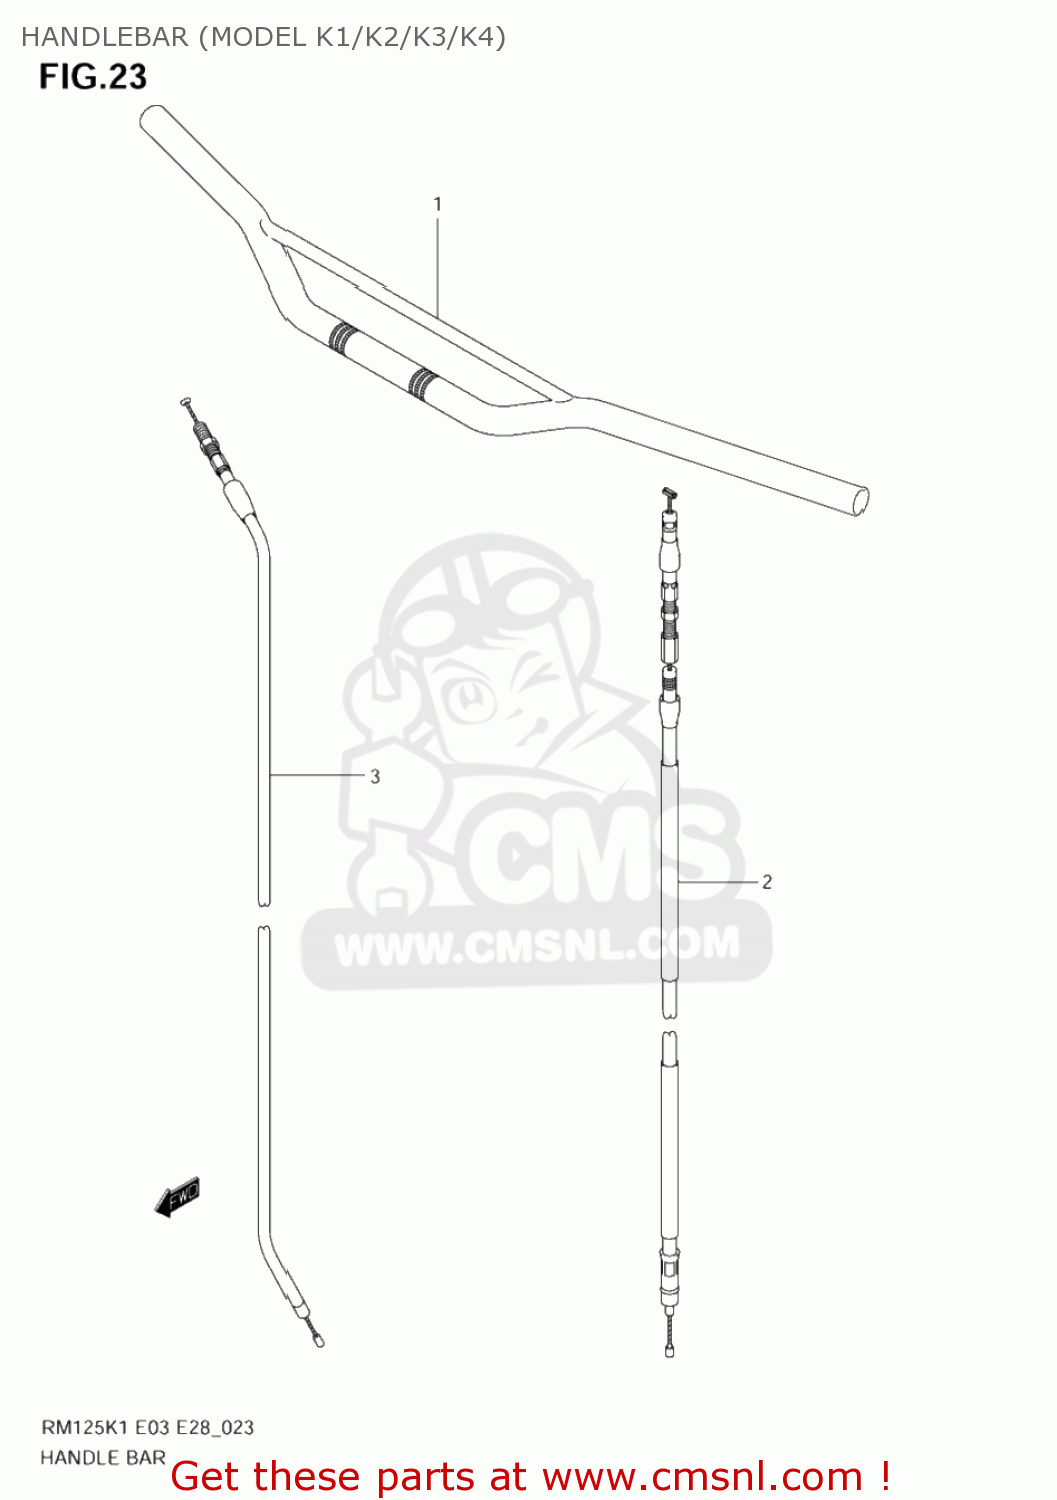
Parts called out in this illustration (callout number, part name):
1	HANDLEBAR(SILVER)
2	CABLE ASSY,CLU
3	CABLE ASSY,THROTTLE
